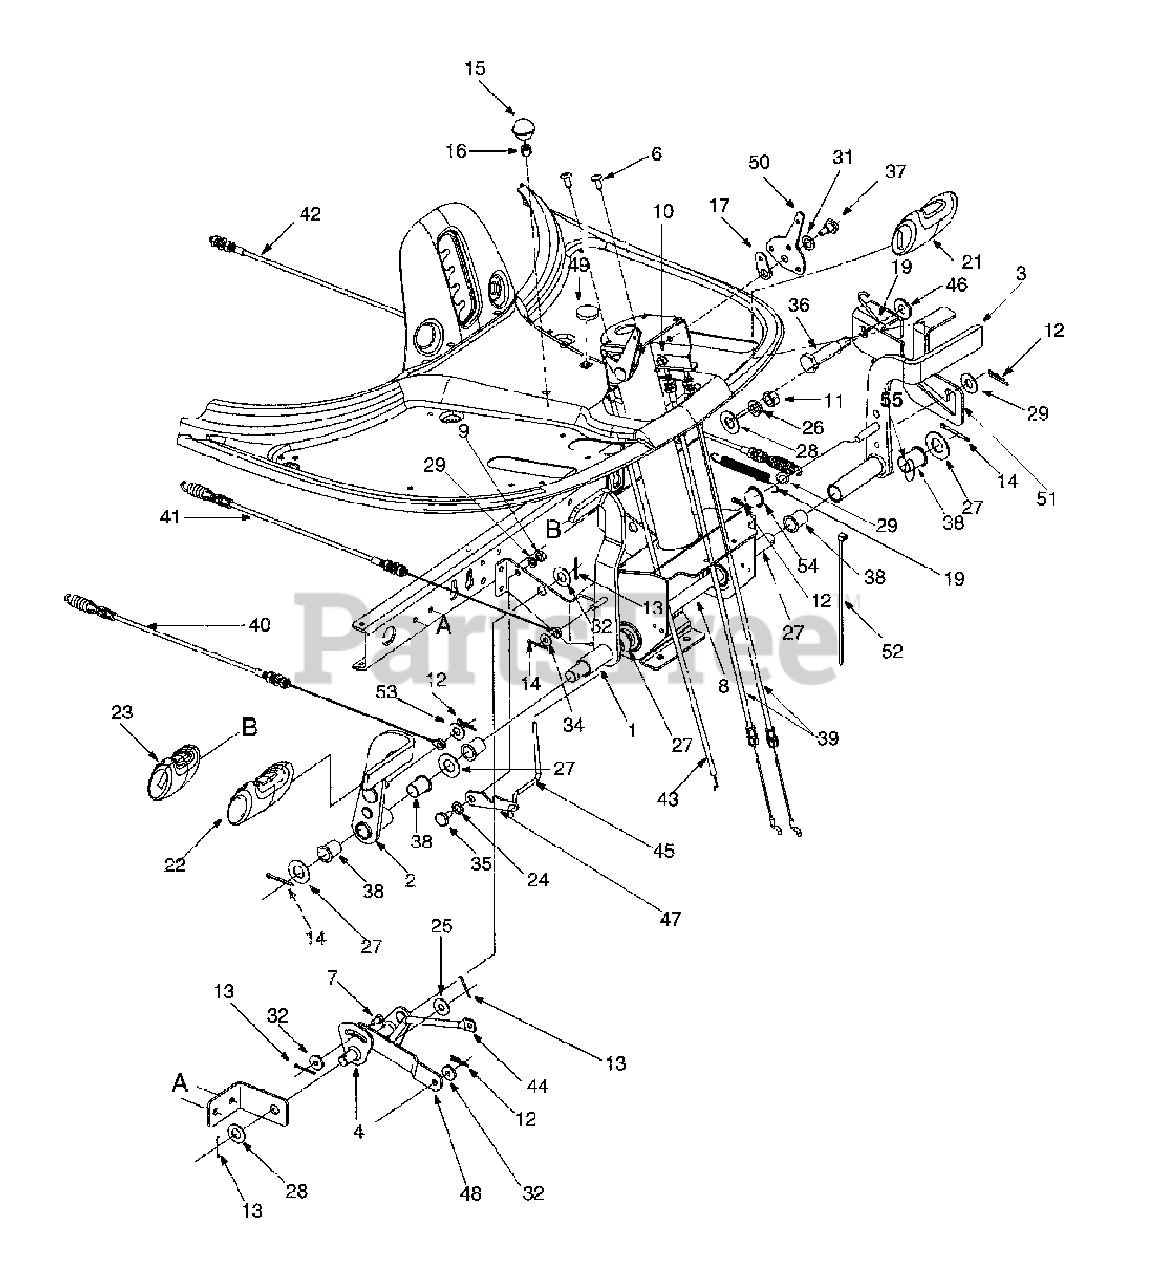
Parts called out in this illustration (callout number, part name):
7	Clevis Pin
8	Shaft
9	Hex Nut 1/4-20
10	Lock Nut 1/4-20
11	Hex Nut 3/8-16
12	Internal Cotter Pin
13	Hairpin Clip
14	Hairpin Clip
15	Ball Knob
16	Snap-on Bushing
17	Stop Lever
19	Torsion Spring
21	Deck Pad
22	Drive Pad
23	Brake Pad
24	Flat Washer 3/8 X .620 X .033
25	5/16 Washer
26	Lock Washer
27	Flat Washer
28	Flat Washer .510 X 1.00 X .060
29	Flat Washer .406 x 1.25 x .10
31	Spring Washer
32	Flat Washer
34	Flat Washer .271 X .630 X .065
35	Shoulder Screw .375 Dia X .18
36	Shoulder Screw
37	Shoulder Screw .375 X .380 X 1/4-20
38	Flange Bearing
39	Shift Cable
40	Variable Drive Cable
41	Brake Cable
42	Deck Cable
43	Throttle Choke Cable: 67"
44	Brake Rod
45	Brake Lock Out Rod
46	Shoulder Spacer
50	Shift Lever
53	Flat Washer .406 I.D. x .875 O.D.
54	Push Cap
55	Flat Washer
